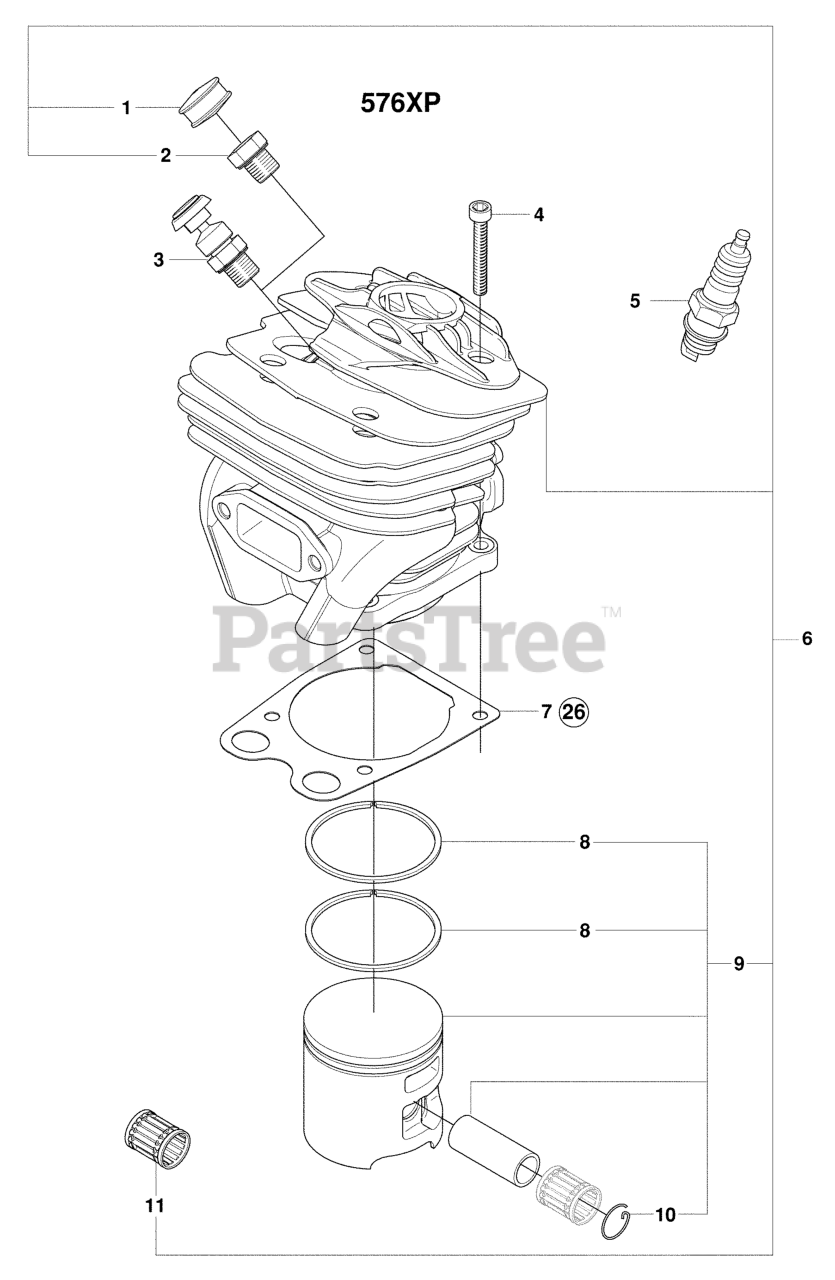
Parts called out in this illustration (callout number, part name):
2	CYLINDER PLUG
3	VALVE
4	SCREW MC6S 5X25
5	SPARK PLUG M14X1.25 NGK BPMR7A
6	CYLINDER ASSY
8	%PISTON RING
9	PISTON
10	WRIST PIN CLIP
11	SUPPORT BUSHING
26	GASKET KIT
